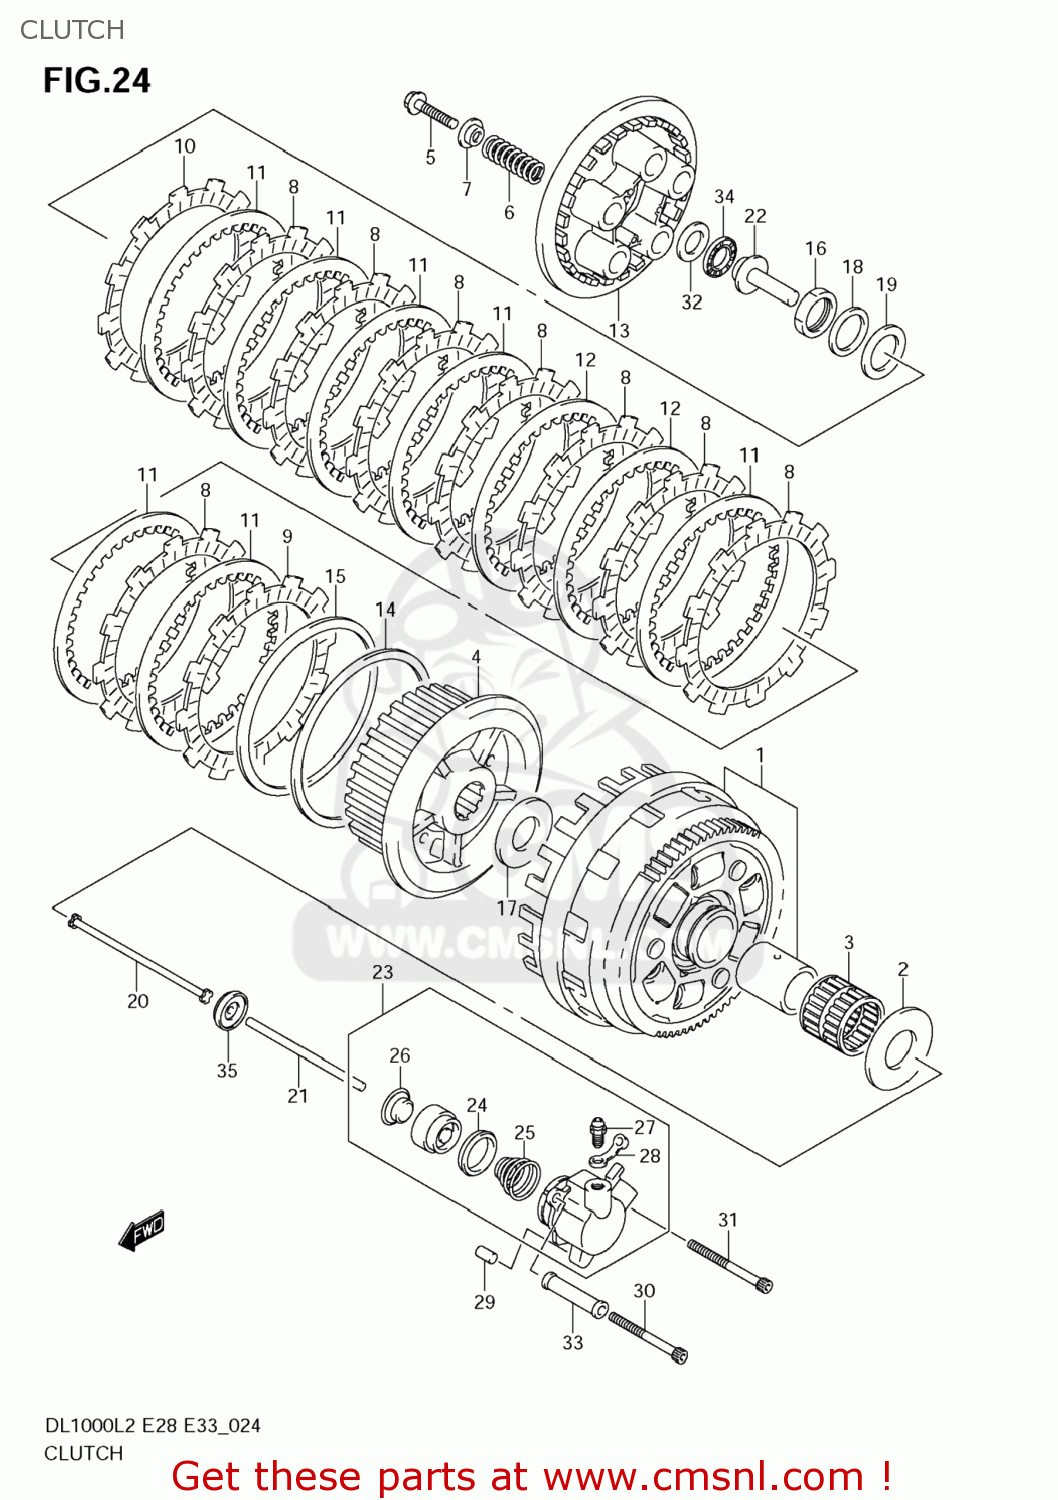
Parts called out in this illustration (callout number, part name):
1	GEAR ASSY,PRI DRIVEN
2	WASHER(25X52X2.5)
3	BEARING(35X40X39.8)
4	HUB,CLUTCH SLEEVE
5	BOLT,CLUTCH SPRING
6	SPRING,CLUTCH
7	WASHER
8	PLATE,CLUTCH DRIVE NO.1 (NAS)
9	PLATE,CLUTCH DRIVE NO.3 (NAS)
10	PLATE,CLUTCH DRIVE NO.2 (NAS)
11	PLATE,CLUTCH DRIVEN NO.1(T:2.0 (NAS)
12	PLATE,CLUTCH DRIVEN NO.2(T:2.3 (NAS)
13	DISC,CLUTCH PRESSURE
14	SEAT,WAVE WASHER
15	WASHER,CLUTCH PLATE WAVE
16	NUT
17	WASHER(25X50X2.5)
18	WASHER
19	SHIM(25X38X1)
20	ROD,CLUTCH
21	ROD,CLUTCH PUSH,L
22	PIECE,CLUTCH PUSH
23	CYLINDER,CLUTCH RELEASE
24	CUP
25	SPRING,CLUTCH CYLINDER
26	COVER,DUST
27	BLEEDER
28	CAP,BLEEDER
29	PIN
30	BOLT
31	BOLT
32	WASHER(15.5X28X1)
33	SPACER,CL RLSE CYL
34	BEARING(15X28X2)
35	SEAL,OIL(6X34X10.5)
